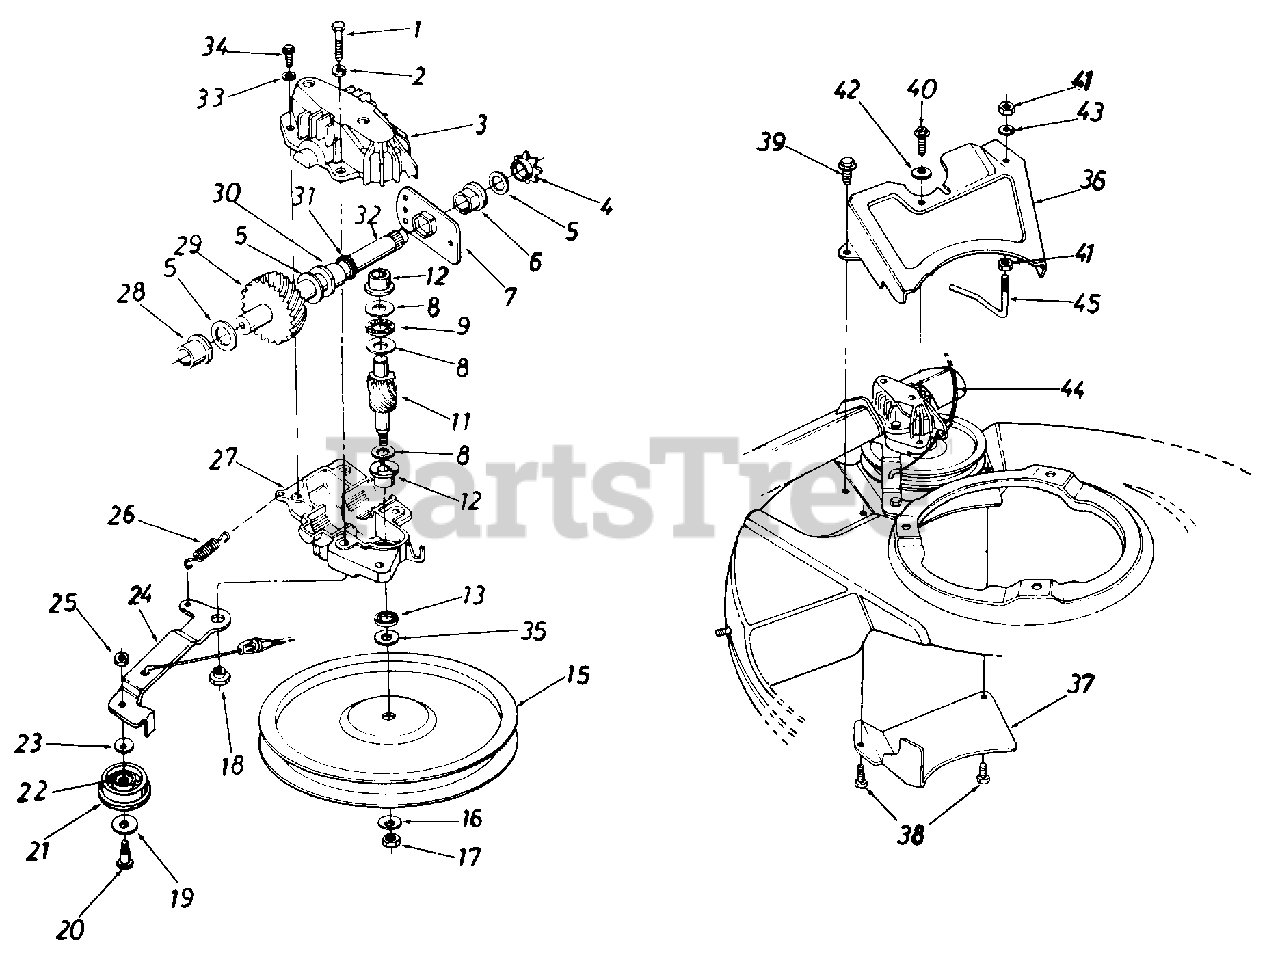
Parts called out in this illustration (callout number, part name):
1	Hex Bolt 1/4-20 x 1.25" Lg.* w/Patch
2	L-Wash. 1/4" I.D.
3	Upper Hsg. Half
4	#48 Sprocket 7 Tooth x 1/2 Pitch
5	Fl-Wash. 5/8" I.D. x .030
6	Hex Flange Brg. .631" I.D.
8	Thrust Wash. .382" I.D. x 70" O.D.
9	Thrust Bearing .375" I.D. x .812" O.D.
11	11 Tooth Helical Gear
12	Flange Bearing
15	Fl-Pulley 5.06" I.D.
16	Bell-Wash. .265" I.D. x 75"
17	Hex Nut 1/4-28 L.H. Thd.
18	Shld. Spacer .375" Dia. x .170
19	Fl-Wash. .390" I.D. x 1.0"
20	Shld. Bolt .375" Dia. x .40"
21	Fl-Idler Plastic 1.50" Dia.
22	Needle Brg. .375" x .31"
23	Bell-Wash. .265" I.D. x 75"
24	Idler Brk't. Ass'y.
25	Hex Patch L-Nut 1/4-28 Thd.
26	Extension Spring 1.12" Lg.
27	Lower Hsg. Half
28	Flange Bearing .56 Dia.
29	33 Tooth Helical Gear
30	Flange Bearing .629 Dia.
31	Oil Seal .625 Dia.
32	Gear Sprocket Shaft
33	L-Wash. #10 I.D.
34	Hex B-Tap Scr. #10 x .62"
35	Hex Washer .26" x .88"
39	Hex AB-Tap Scr. 1/4 x .50" Lg.
40	Hex B-Tap Scr. 1/4 x .62" Lg.
41	Hex Nut 1/4-20 Thd.*
42	Bell-Wash. .265" I.D. x 75"
43	L-Wash. 1/4" I.D.*
44	S.P. Cable-48" Lg.
45	S.P. Belt Guard
